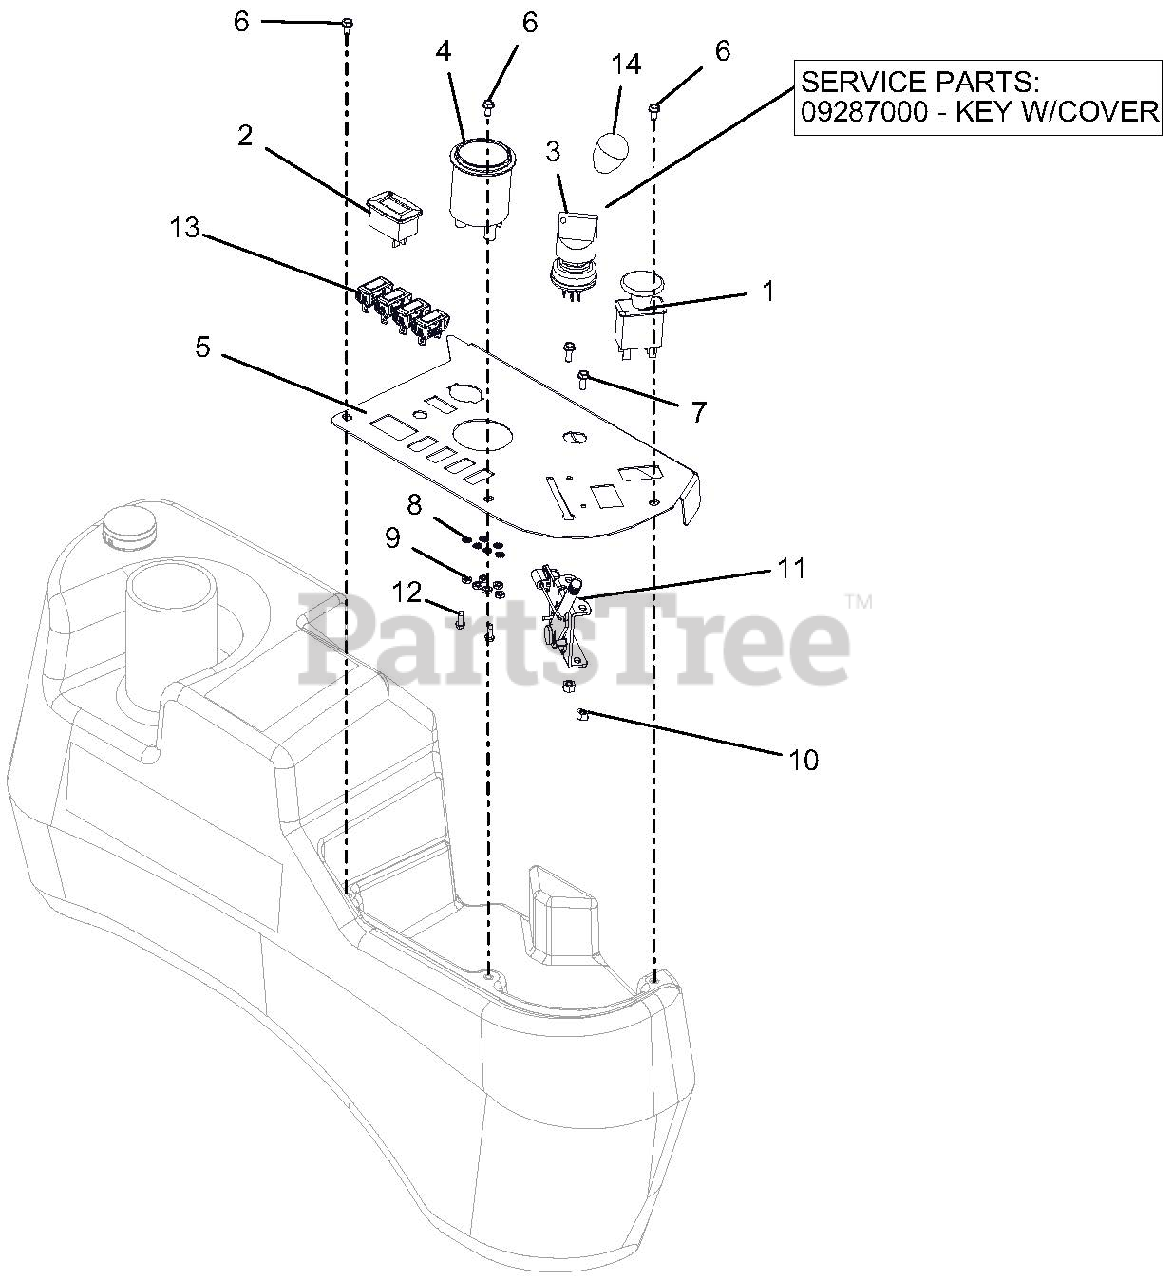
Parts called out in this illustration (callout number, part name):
1	SWITCH, CLUTCH
2	METER, HOUR W/MAINTENANCE
3	SWITCH, IGNITION
3	KEY, W/ SHIELD
4	GAUGE, TEMP
5	DIESEL CONTROL PANEL - BLK
6	SCR-MCH 10-24X.38 HWHSTAINLESS
7	@SCR-MCH 10-24X.50 HWH YWZC
8	WSHR-LK-EXT #6 STAR
9	NUT-HEX MACH #6-32
10	@NUT-LK-NYL 10-24 W/INSRT YWZC
11	CABLE-THROTTLE 47.37"
12	@SCR-TAP 8-32X.50 HWH TR YWZC
13	LIGHT,INDICATOR
14	KNOB-CONTROL-BLACK .38-16X.50
